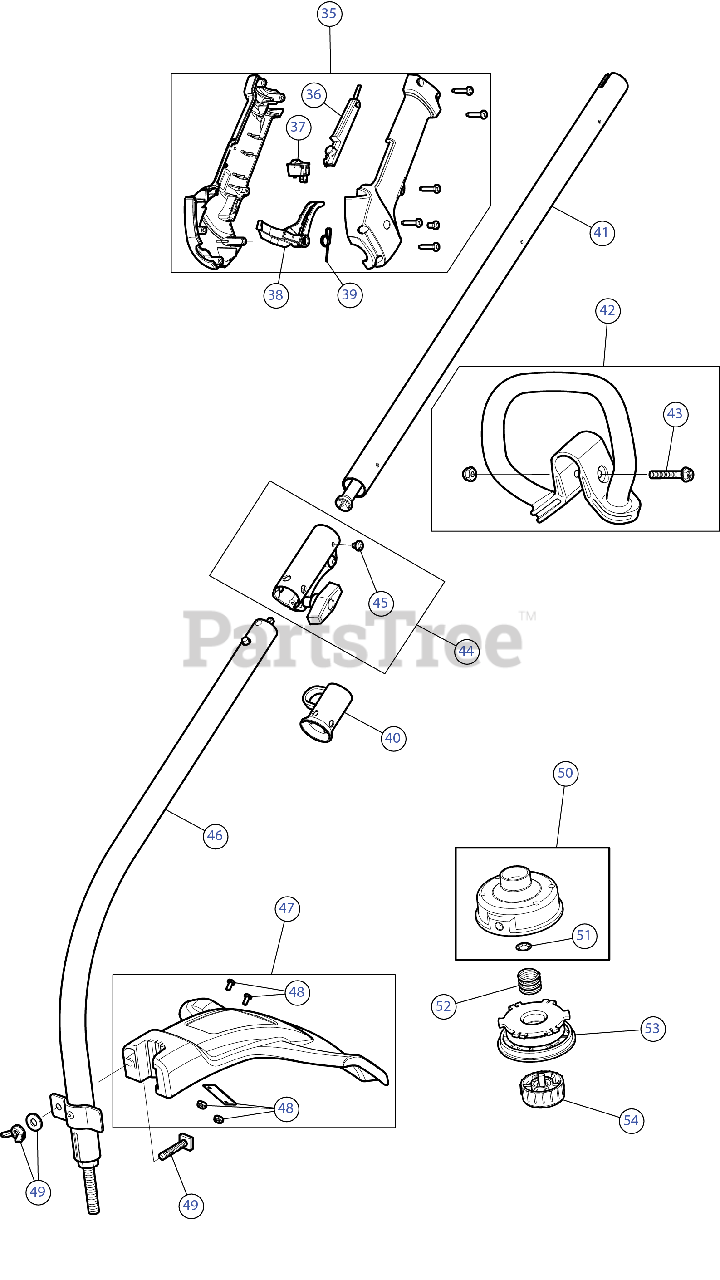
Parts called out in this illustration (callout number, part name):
35	THROTTLE GRIP ASSEMBLY
36	THROTTLE LVR LKOUT
37	SW, MOMENTARY ON/O
38	THROTTLE TRIGGER
39	SPRING TRIG
41	BOOM ASSEMBLY UPR
42	D-HANDLE
43	BOLT 1/4-20X1 1/2
44	SPLIT BOOM COUPLER KIT
45	SCREW, 10-32X.250 TA
46	BOOM ASSEMBLY W/FLEX DRIVE SHAFT
47	GUARD ASSEMBLY
48	ASSEMBLY, BLADE
49	BLADE GUARD MOUNTING HARDWARE
50	REEL:OTR W/RET
51	RETAINER .625 OD 2
52	SPRING-SPOOL
53	REEL&LINE ASM W/.095 TWIST
54	BUMP HEAD KNOB ASSEMBLY
